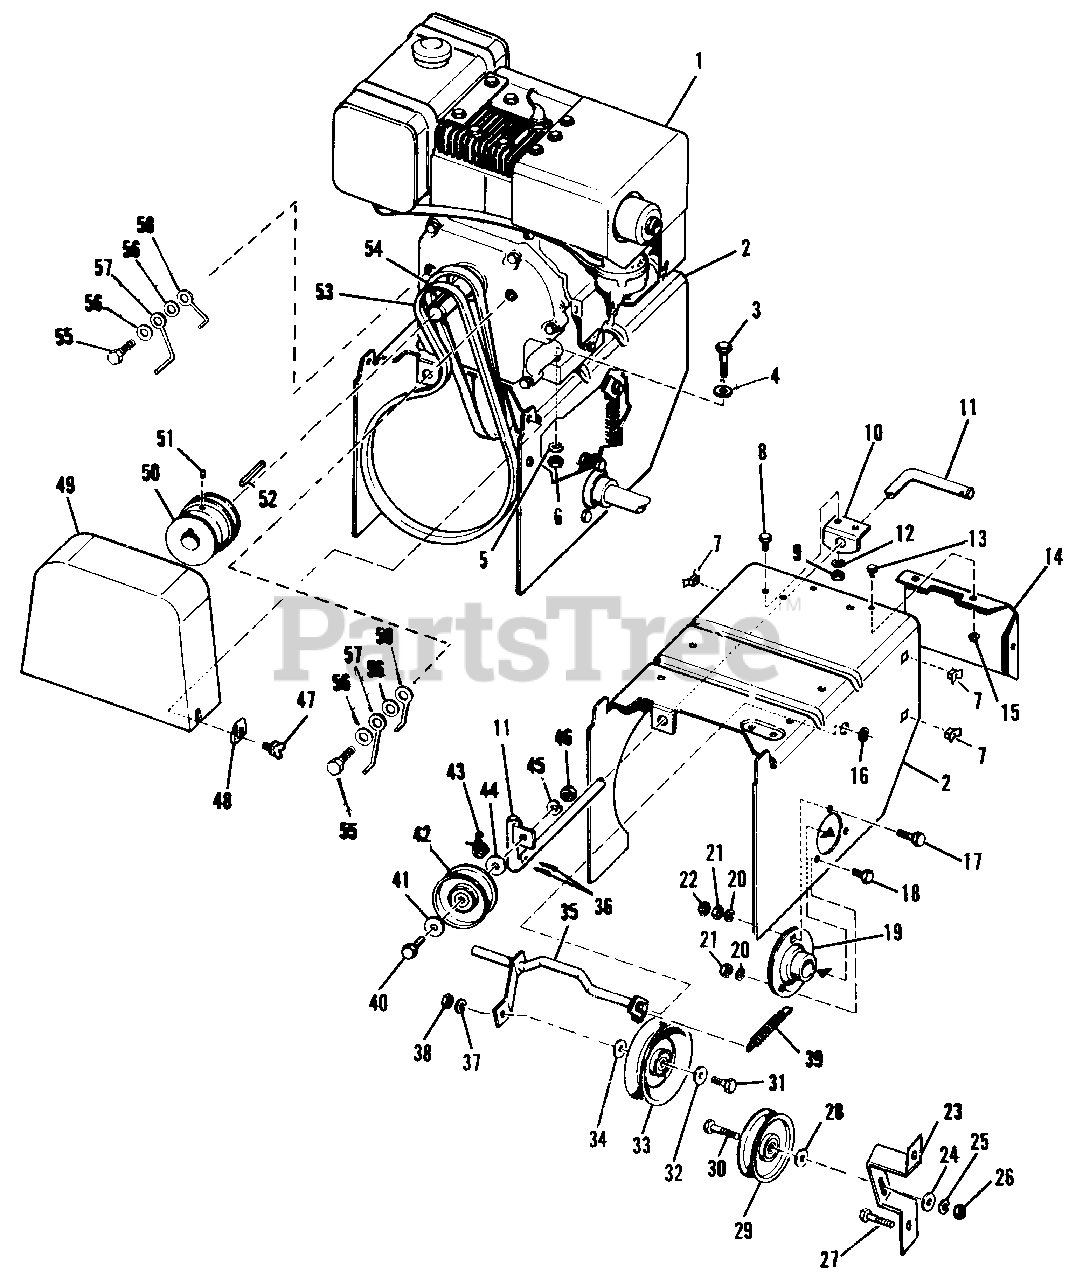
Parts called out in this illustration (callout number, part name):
2	ENGINE BASE & FRAME (990560 Only)
3	Capscrew, Hex Hd., 5/16"-18 NC x 1 3/4" lg.
4	WASHER-flat, 5/16
5	Lockwasher, External 1/4" (Mfg. Nos. 953 & 954)
6	Hex Nut, Full, 5/16"-18" NC (For "725" Only-Rear)
7	Nut, Tinnerman, 5/16"-18 N.C.
8	Screw, Cap, Hex., 5/16"-18 N.C. x 5/8" lg.
9	NUT, hex, 5/16-18
10	BRACKET, Angle
11	ROD ASSY., Clutch, Auger
12	WASHER-lock, 5/16
13	SCREW-self tapping, No. 14AB x 5/8
14	COVER, Back (990430 & 990560 Only)
15	NUT, Speed, Tinnerman
16	RING-retaining
17	Capscrew, Hex Hd., 3/8"-16 NC x 1-1/4" lg. (For "725" Front)
18	CAPSCREW, 7/16"-20 NF x 3/4" Hex Head, Large
19	BEARING, Ball (990560 Only)
20	Lockwasher, 3/8" (Mfg. Nos. 920 & 953)
21	Nut-Hex.-Full 3/8"-16 N.C. Henry #916950
22	SCREW, Hex Head, 3/8-16 x 1-1/4
23	BRACKET-idler
24	WASHER-flat, 5/16
25	WASHER-lock
26	Nut-Hex.-Full 3/8"-16 N.C. Henry #916950
27	PIN-PISTON/STD
28	SPACER (990483 & 990559 Only)
29	PULLEY, Idler
30	SCREW, Hexagon Head Cap 3/8"-16 N.C. x 1-1/2" Large
31	SCREW-3/8-16x 2 1/4
32	Plain Washer, 5/16" (Mfg. No. 920)
33	PULLEY, Idler
35	CLUTCH PULLEY PIVOT
36	Cotter Pin, 5/32" x 1" lg.
37	WASHER-lock, 3/8
38	Nut-Hex.-Full 3/8"-16 N.C. Henry #916950
39	SPRING-tension
40	SCREW-3/8-16 x 1 3/4
41	WASHER-flat, 5/16
42	PULLEY-idler
43	SPRING, Torsion
44	SPACER
45	Lockwasher, 3/8" (Mfg. Nos. 920 & 953)
46	Nut, Lock, Hex Hd., Full, 3/8"-l6 N.C.
47	SCREW-thumb, 5/16-18 x 3/4
48	Tinnerman Nut, #C31280-5618-1
49	COVER, Engine Pulley
50	PULLEY-engine
51	Screw, Set, Cup Point Socket Head, 5/16"-18 NC x 3/8" lg.
53	BELT-V
54	BELT, V
55	SCREW-hex, 5/16-24 x 1
56	Plain Washer, 5/16" (Mfg. No. 920)
57	STOP-belt
58	STOP, Belt
59	STOP-belt
